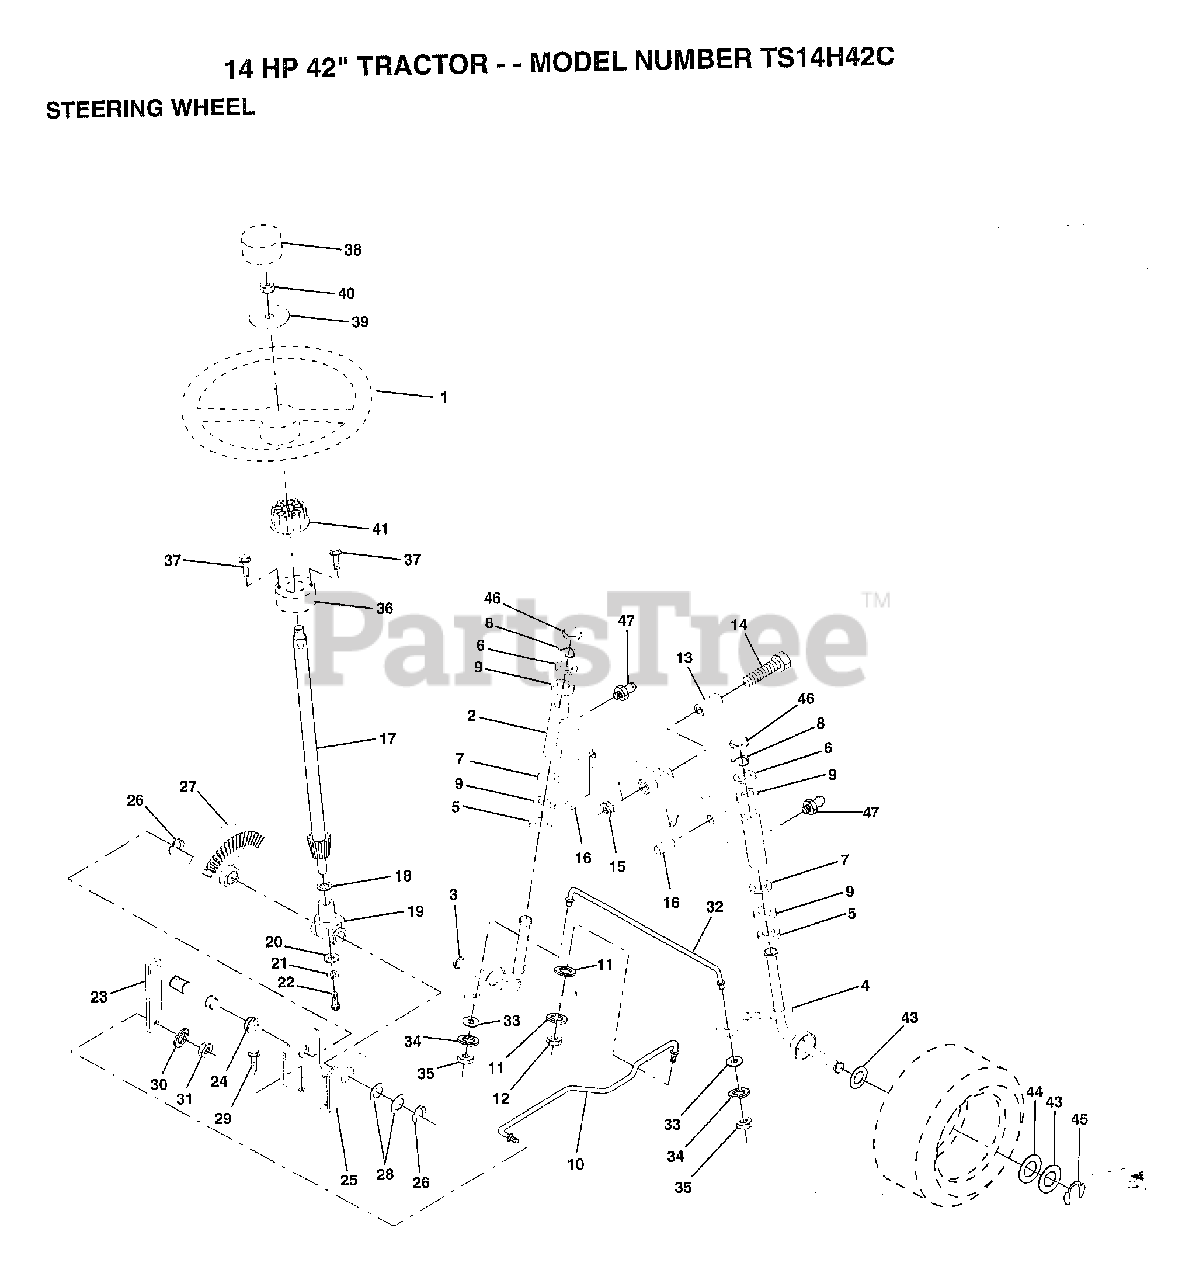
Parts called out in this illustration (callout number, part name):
2	AXLE ASM FRONT
3	SPINDLE LH
4	SPINDLE RH
5	WASHER .T
6	WASHER
7	WASHER
8	RING
9	COL. SRTG. BEAR.
11	LOCKWASHER
13	BEARING
14	BOLT HEX 5/8-11
15	"NUT-LOC,FLANGE LT"
16	AXLE PIN
17	STEERING SHAFT
18	THRUST WASHER
19	SUPPORT.SHAFT
21	LOCKWASHER
22	"SCREW,SPECIAL"
24	NYLINER T
25	"BRKT,STEERING"
26	RING
27	GEAR SECTOR
28	WASHER .T
29	SCREW
30	LOCKWASHER
32	TIE ROD
33	WASHER M
34	LOCKWASHER
35	NUT.LOCK.5/16-24
38	"INSERT,STR WHEEL"
39	WASHER
41	ADAPTER LT
43	WASHER
44	WASHER
45	RING
46	CAP
47	ZERK M
